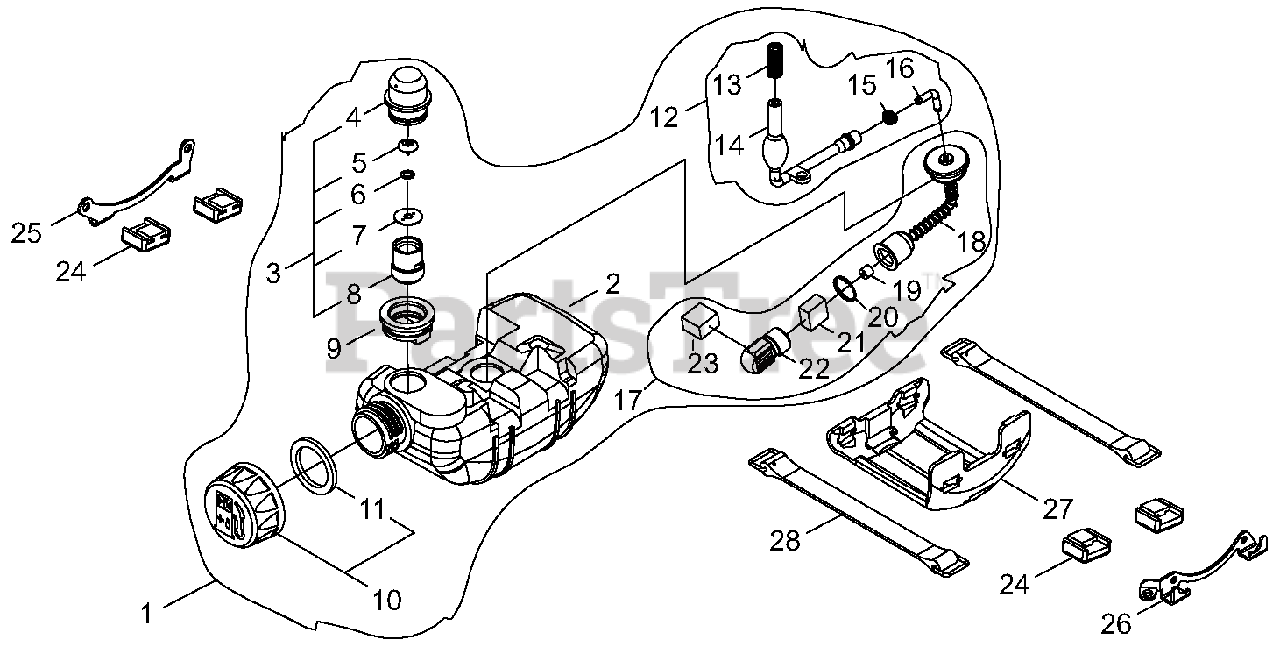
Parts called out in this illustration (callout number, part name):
1	TANK ASSY, FUEL
2	TANK, FUEL
3	VENT ASSY
4	CAP, VENT
5	VENT ASSY
6	WASHER
7	RETAINER
8	HOLDER, VENT
9	GROMMET, VENT
10	CAP ASSY, FUEL
11	GASKET, FUEL CAP
12	PIPE ASSY, FUEL
13	CLAMP
14	PIPE, FUEL
15	CLIP
16	CONNECTOR, PIPE
17	FILTER ASSY, FUEL
18	PIPE, FUEL
19	VALVE, CHECK
20	CLIP
21	FILTER, FUEL - B
22	WEIGHT
23	FILTER, FUEL - A
24	CUSHION, FUEL TANK
25	BRACKET M
26	BRACKET S
27	GUARD, FUEL TANK
28	STRAP, FUEL TANK
